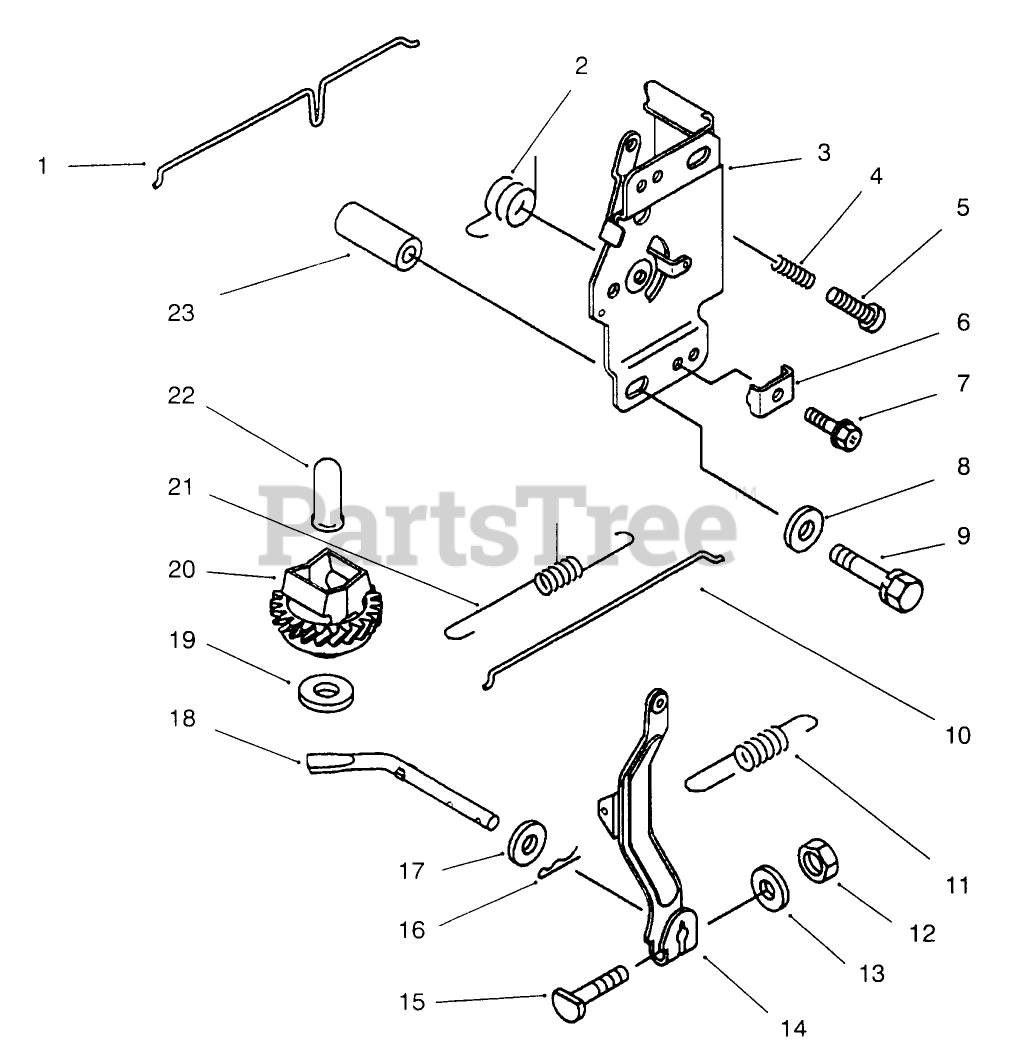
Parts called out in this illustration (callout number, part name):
1	LINK-Choke
2	Spring
3	Panel Incl #2 4-7
4	Spring
5	Screw
6	Clamp
7	BOLT (5X18)
8	Washer
9	Bolt
10	Link
11	Spring
12	NUT-HEX (6mm)
13	Washer-Plain (6mm)
14	Arm ASM
15	Bolt (6X28)
16	Pin-Snap (1.2 X 21.2)
17	WASHER (6.5X11.5X2.0)
18	Arm-Pivot
19	Washer (6.2X20X0.5)
20	Governor ASM
21	Spring
22	Sleeve
23	Collar
